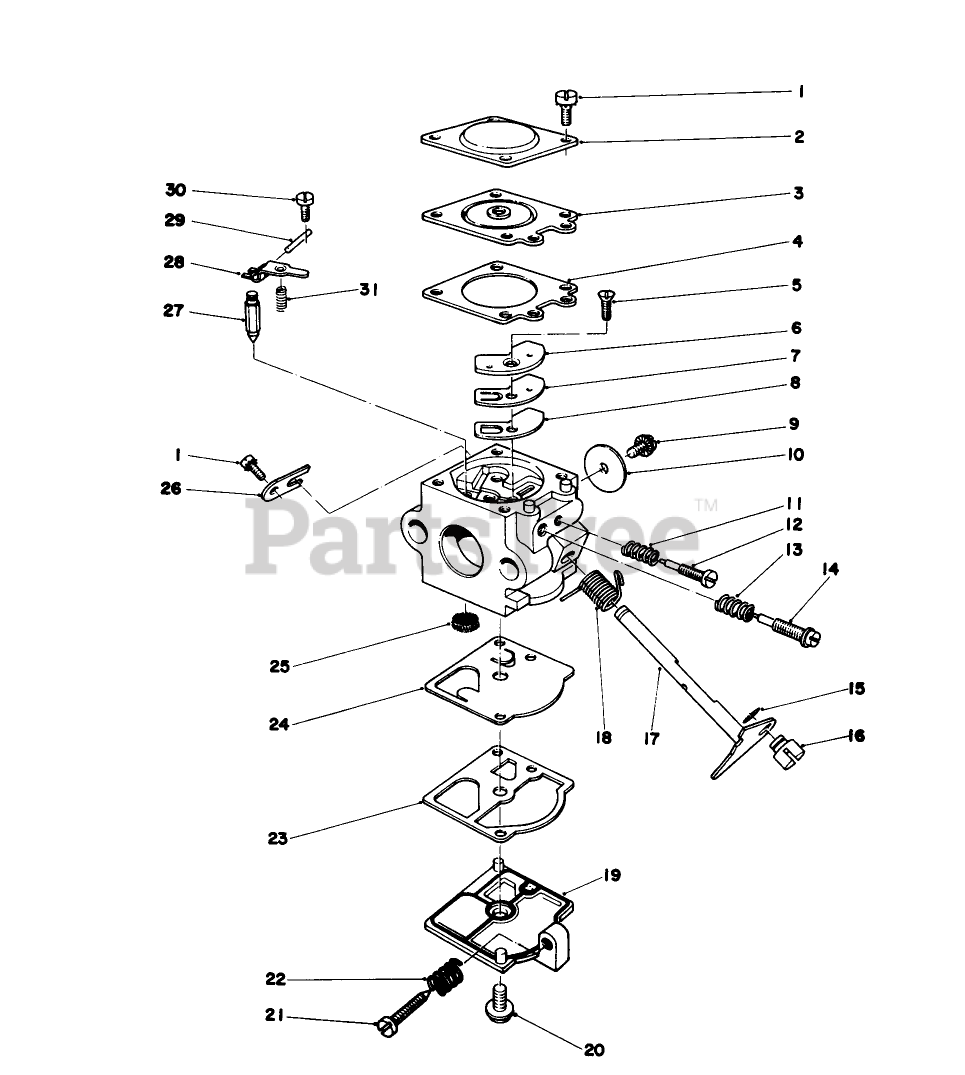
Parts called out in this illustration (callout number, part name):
1	Screw
2	Cover, Diaphragm
3	METERING DIAPHRAGM
4	Gasket, Diaphragm
5	Screw-Circuit Plate
6	Plate, Circuit
7	Diaphragm Circuit Plate
8	Gasket-Circuit Plate
9	Screw
10	Valve Throttle
11	Spring, Needle
12	Idle Needle
13	Spring, HS Needle
14	Needle, High Speed
16	Swivel
17	THROTTLE SHAFT ASM
18	Spring-Throttle Lever
19	Cover, Fuel Pump
20	Screw
21	Screw, Idle Adjust
22	Spring, Idle Screw
23	PUMP GASKET
24	Diaphragm Fuel Pump
25	Screen Inlet
26	Clip Throttle Shaft
27	INLET NEEDLE VALVE
28	Lever Metering
29	Metering Lever Pin
30	Screw-Metering Pin
31	Spring, Lever
